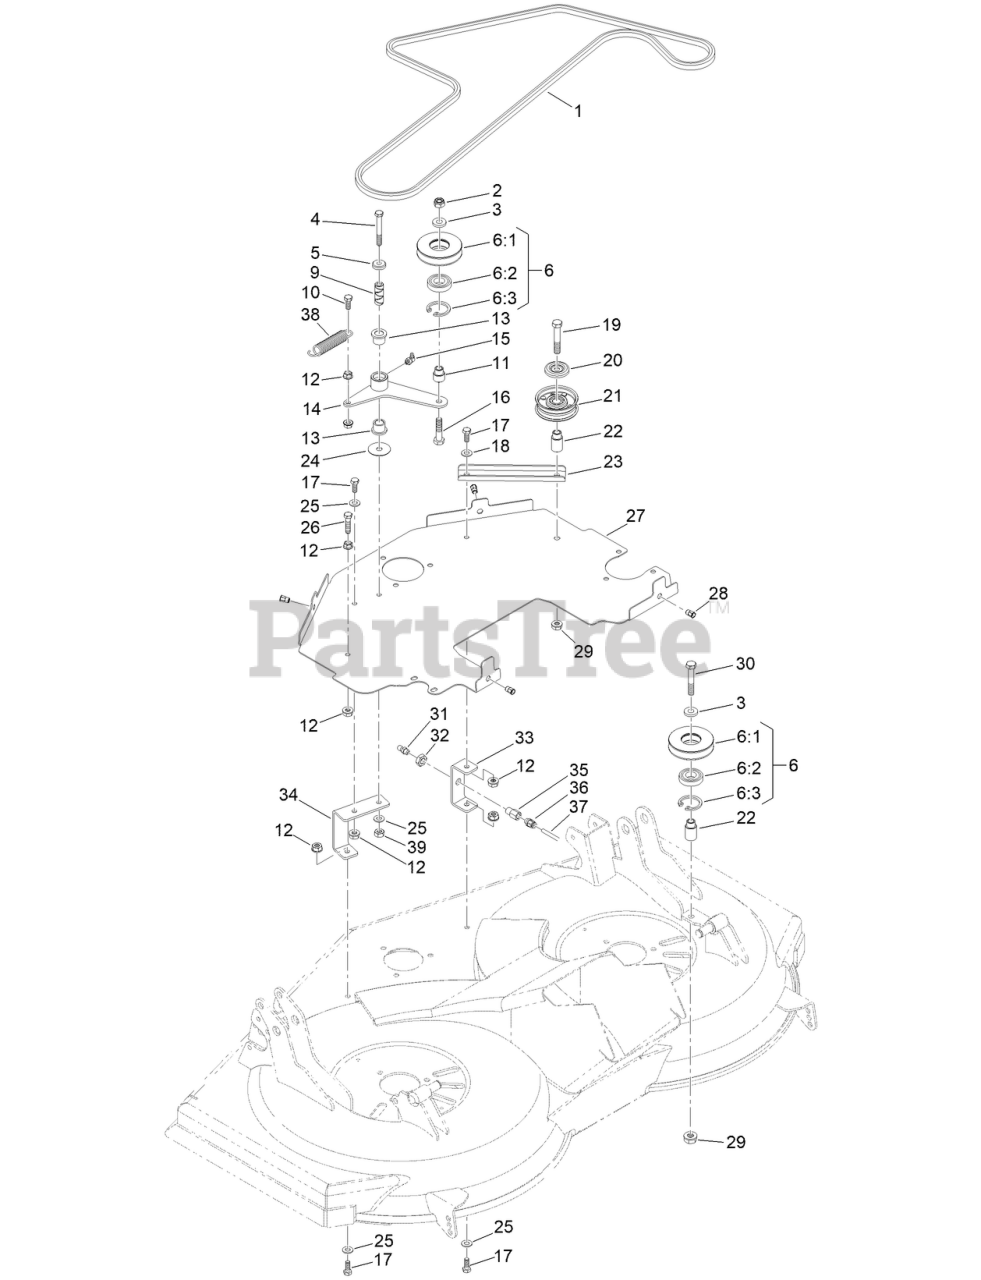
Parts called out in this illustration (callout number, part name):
1	BELT, DECK
3	WASHER
5	WASHER
6	PULLEY ASSY, BELT TENSIONER
6:1	PULLEY, BELT TENSIONER
6:2	BEARING
6:3	RETAINER
9	SPACER
11	BUSHING
13	BUSHING
14	BRACKET, DECK BELT TENSIONER
15	NIPPLE, GREASE
16	SCREW, HH CAP
18	WASHER
20	GUARD, IDLER
21	PULLEY, IDLER
22	BUSHING
23	REINFORCEMENT BRACKET
25	WASHER
27	SHELL, DECK
28	INSERT-THREADED
30	SCREW-HH
31	FITTING-GREASE
33	BRACKET, SHELL RH
34	BRACKET, SHELL LH
35	FITTING
36	FITTING-STRAIGHT
38	SPRING-EXTENSION
